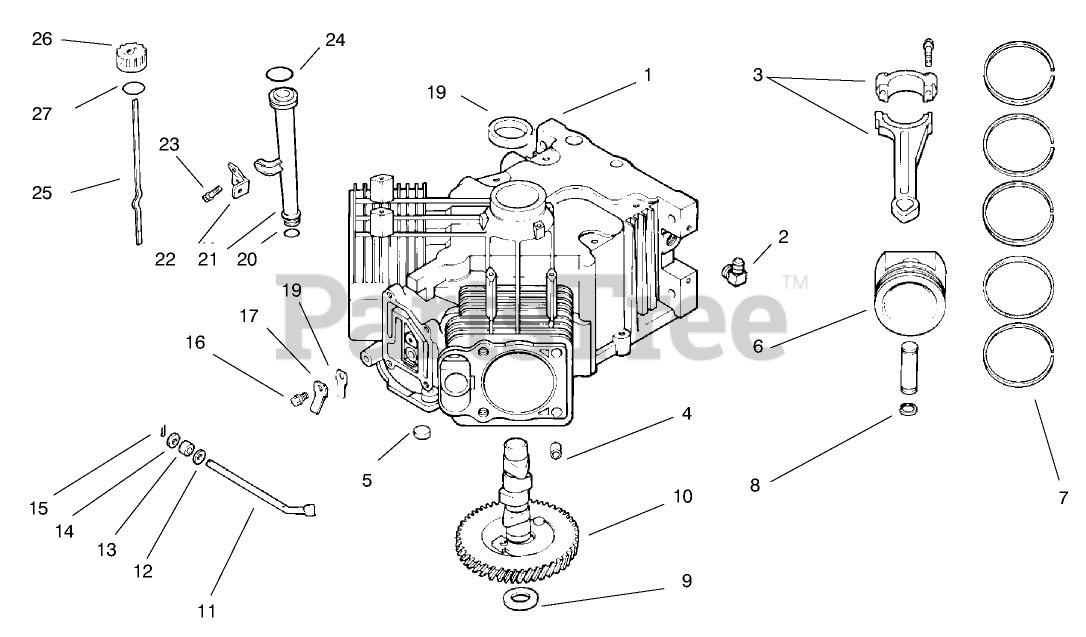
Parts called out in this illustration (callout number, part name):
1	Miniblock
2	Fitting
3	Connecting Rod STD
3	Connecting Rod .25
4	Pin-Dowel
5	Plug
6	Piston ASM STD INC4/7/8
6	Set-Piston w/Ring .25
6	Piston ASM .50 INC4/7/8
7	Ring Set(Std.)
7	Set-Ring .25
7	Set-Ring .50
8	Retainer-Piston Pin
9	Shim-Camshaft
10	Camshaft
11	Shaft-Governor Cross
12	Washer
13	Seal-Cross Shaft
14	Washer
15	Pin-Hitch
16	Screw
17	Retainer-Reed
18	Beed-Breather
19	Seal-Oil
20	"O"Ring
21	Tube-Oil Fill
22	Bracket-Oil Tube
23	Screw
24	"O"Ring
25	Dipstick INC 26-27
26	Kit-Oil Fill Cap
27	"O"Ring
